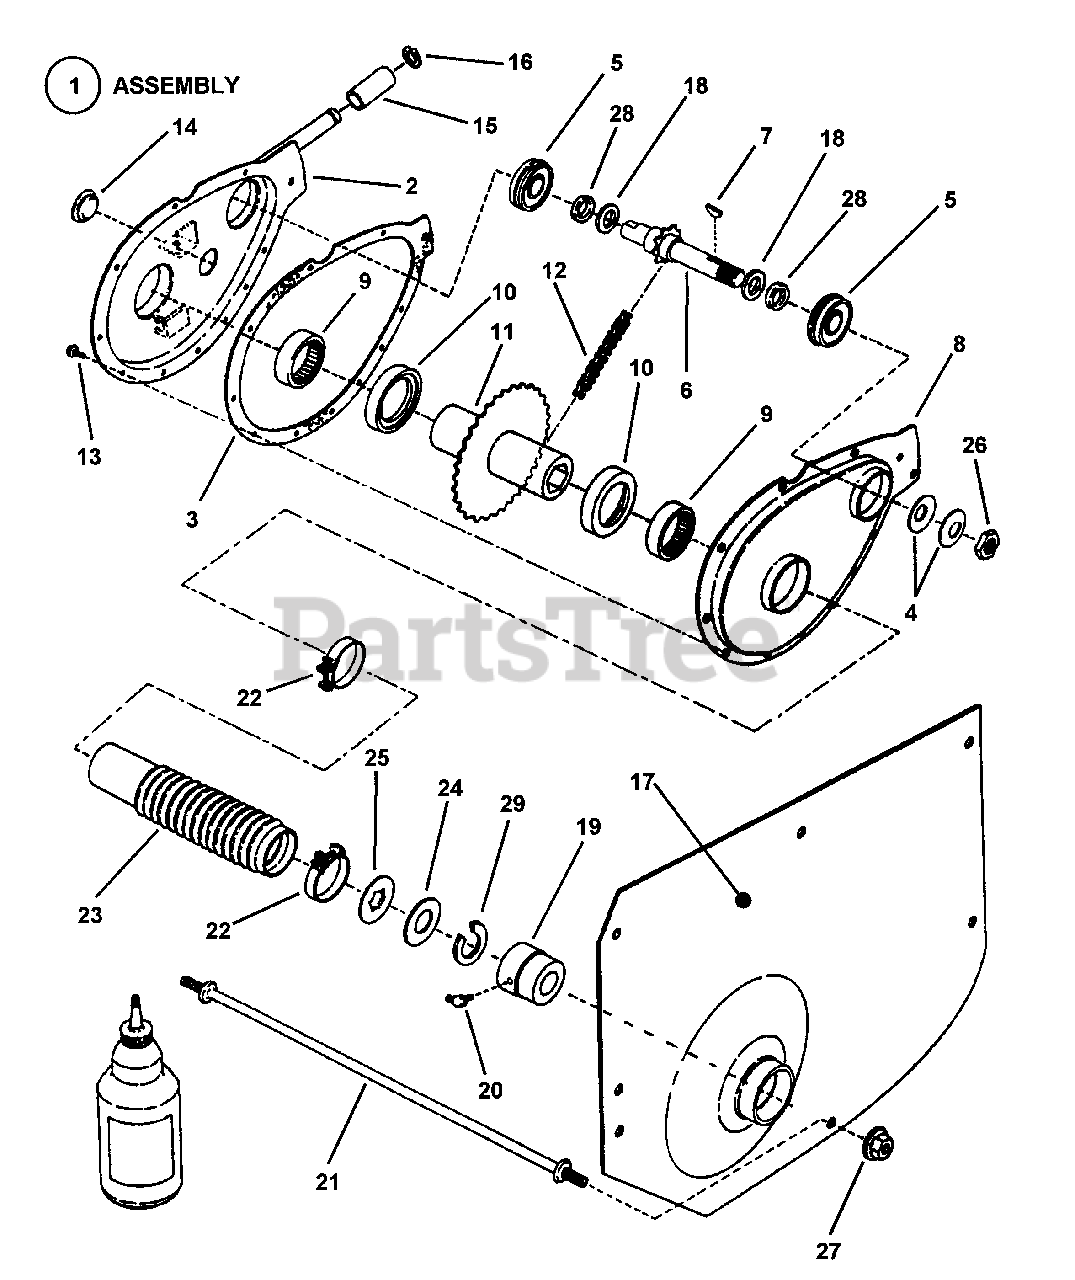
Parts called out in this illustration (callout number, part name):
1	ASSEMBLY, Chain Case
2	CASE, Sprocket
3	GASKET, Case Cover
4	WASHER, Belleville
5	BEARING, Ball
6	SPROCKET & SHAFT
7	KEY, 1/8 x 5/8" Woodruff
8	COVER, Chain Case
9	BEARING, Needle
10	WASHER, Nylon Thrust
11	HUB & SPROCKET
12	CHAIN
13	SCREW, #10-24 x 1/2" Hex Washer Self-Tap (Torx)
14	PLUG, Oil Fill & Check
15	ROLLER
16	RING, 1/2" External Retaining (Heavy Duty)
17	FENDER, Left Hand (1.628" internal diameter hole)
18	WASHER, Shim
19	BEARING, Left Hand Fender
20	FITTING, Lube
21	ROD, Cross-Tie
22	CLAMP, Boot
23	BOOT, Oil Seal
24	WASHER, Thrust Nylon
25	WASHER, Thrust
26	NUT, 5/8-18 hex Lock
27	NUT, 5/16-24 Hex Flange Lock
28	O-RING
29	WASHER, Shim
